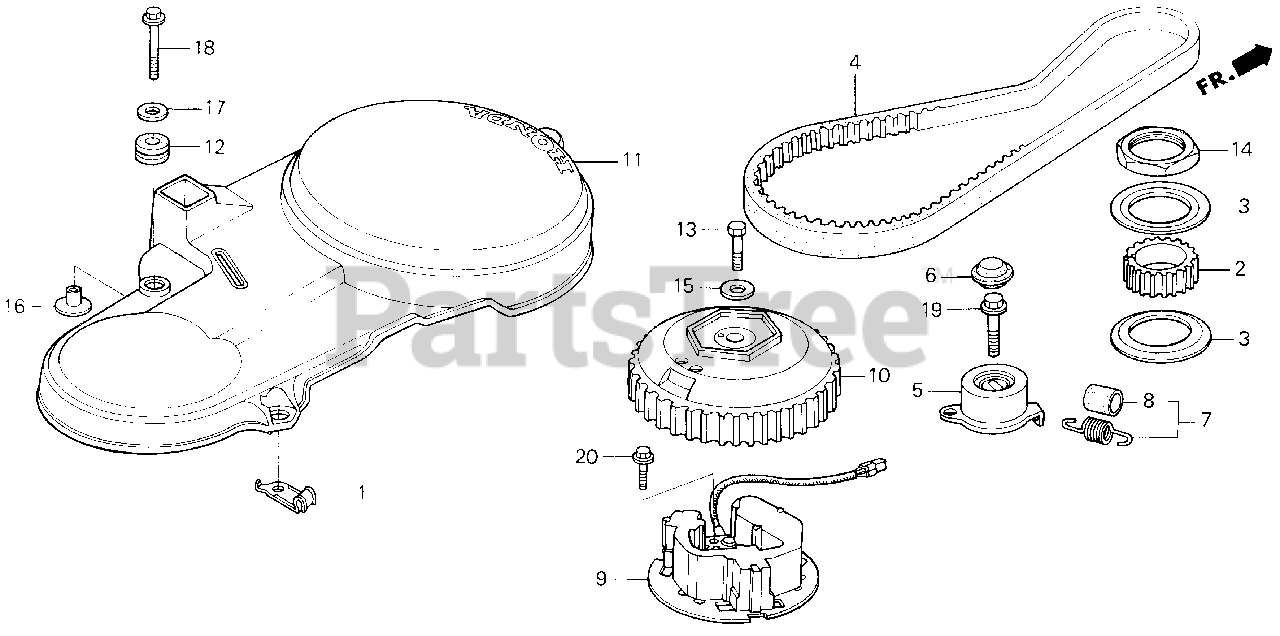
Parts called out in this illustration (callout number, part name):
1	CLAMP, TUBE
2	PULLEY, TIMING
3	PLATE, TIMING BELT GUIDE
4	BELT, TIMING
5	TENSIONER, TIMING BELT
6	CAP, TIMING BELT TENSIONER
7	SPRING, TIMING BELT ADJUSTING
8	BOOT, SPRING
9	COIL ASSY., PULSER
10	ROTOR, PULSER
11	COVER, FLYWHEEL
12	GROMMET, CASE (LOWER)
13	BOLT, FLANGE (10X32)
14	NUT, LOCK (48MM)
15	WASHER (10X28X5)
16	COLLAR, IGNITION CONTROL MODULE CASE
16	COLLAR, MODULE IGNITION CONTROL CASE (CDI)
17	WASHER, PLAIN (6MM)
18	BOLT, FLANGE (6X25)
19	BOLT, FLANGE (10X38)
20	BOLT, FLANGE (6X12)
